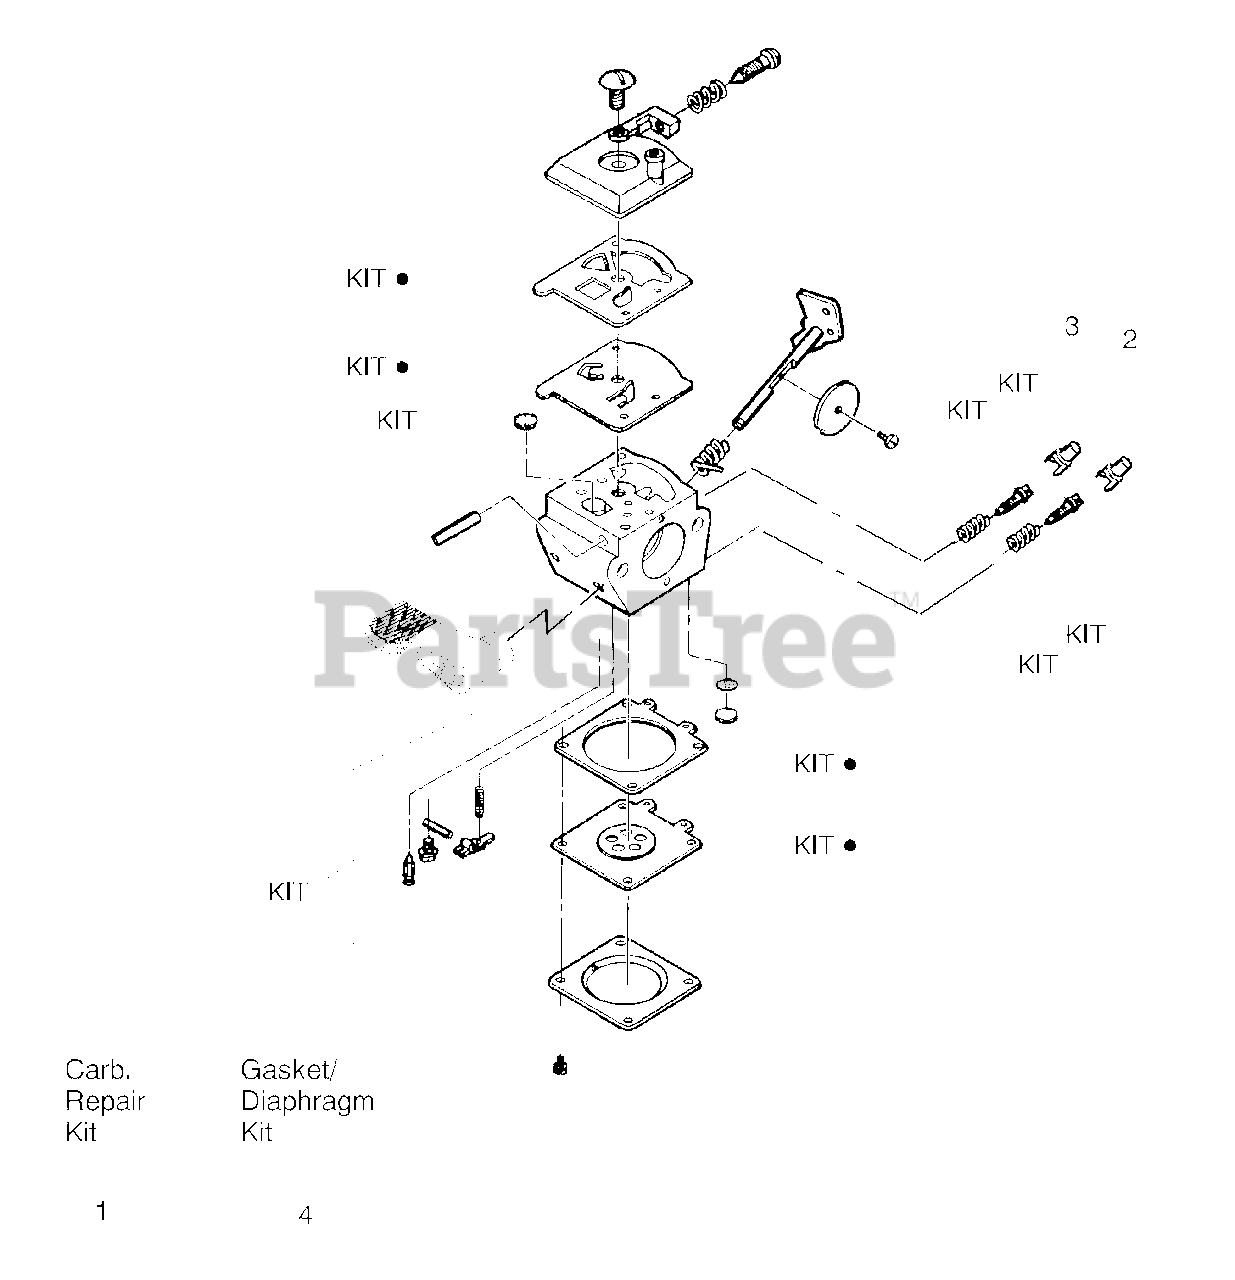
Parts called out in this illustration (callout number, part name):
1	Carburetor Repair Kit
2	Limiter Cap-Low (tan)
3	Limiter Cap-High (Brown)
4	Gasket/Diaphragm Kit
